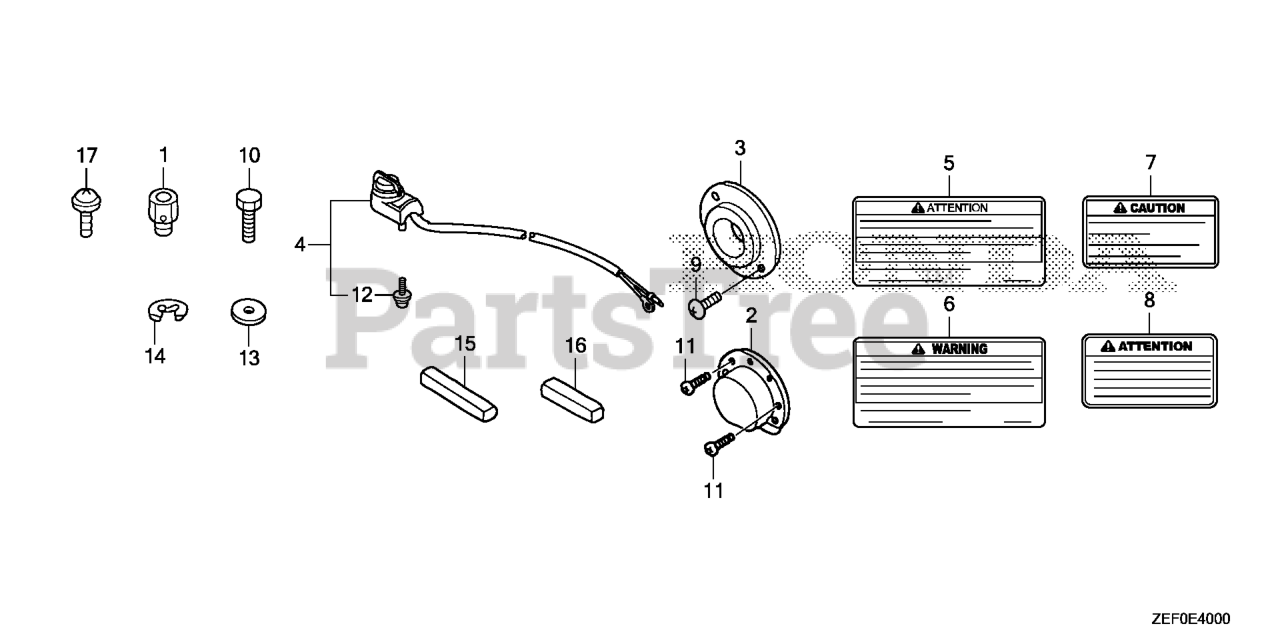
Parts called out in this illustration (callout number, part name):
5	MARK, OPERATOR CAUTION
8	MARK, EX. CAUTION (FRENCH)
16	KEY (4.78X4.78X38)
